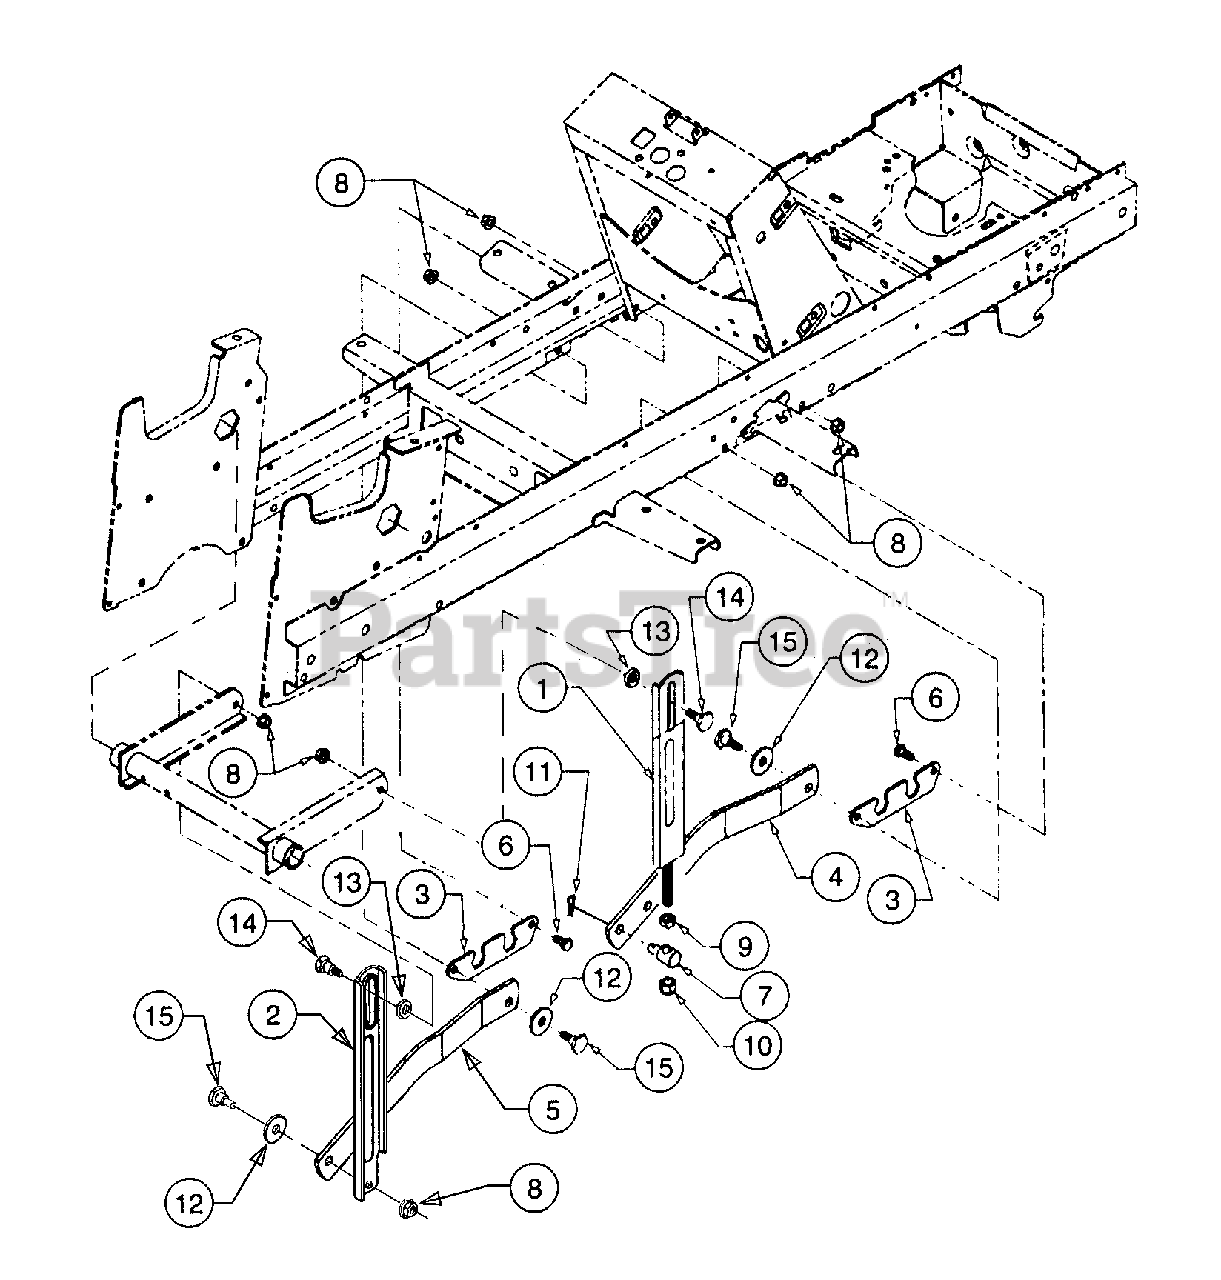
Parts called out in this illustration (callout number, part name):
7	Ferrule, Adjustment
8	Nut, Hex Flange Lock, 3/8-16
9	Nut, Hex Jam, 1/2-13 GR5
10	Nut, Hex Insert Lock, 1/2-13
11	Pin, Internal Cotter
12	Washer, Flat, .5 x 1.5 x .15
13	Washer, Flat, .531 x .875 x .15
14	Bolt, Shoulder
15	Bolt, Shoulder
